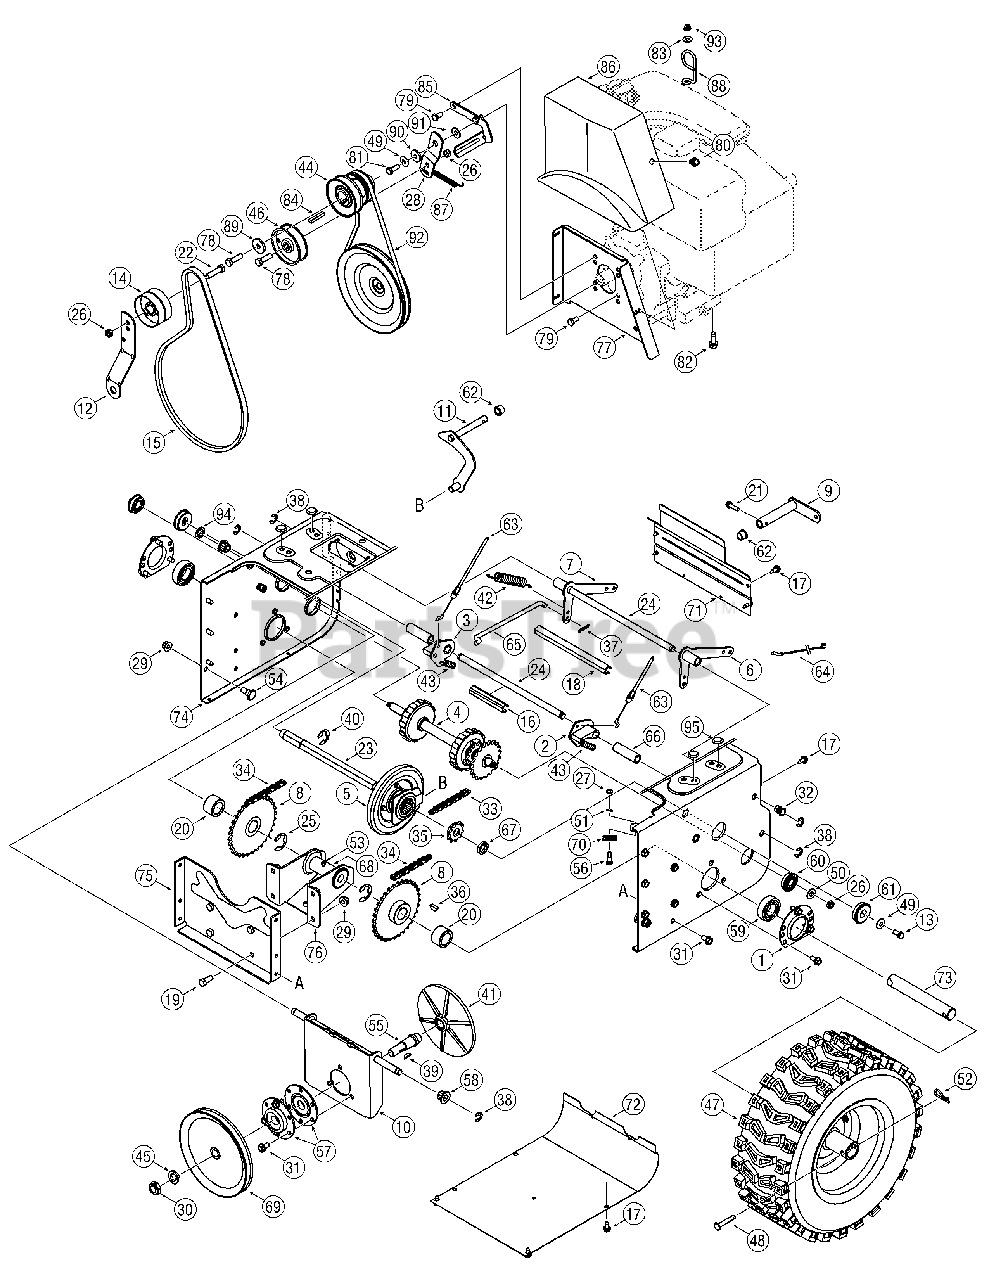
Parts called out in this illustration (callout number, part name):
1	Housing, Bearing
2	Dogg, Steering Drive, LH
3	Dogg, Steering Drive, RH
4	Shaft Assembly, Steering
5	Assembly, Friction Wheel
11	Rod Assembly, Shift
12	Brkt., Idler, Auger
13	Screw, Hex Cap Lock,
14	Idler, Flat, 2.75 OD
15	V-Belt, 1/2 x 44.0
16	Spcr., .51 ID x 3.66 Lg.
17	Screw, Hex Wash.
18	Spcr., .51 ID x 7.895 Lg.
19	Screw, Hex Cap, 3/8-16
20	Spcr., 1.0 ID x 1.50 OD
21	Screw, Hex, 1/4-20 x 1.00
22	Screw, 3/8-24 x 1.50
23	Shaft, Hex Drive
24	Shaft, Actuator
25	Ring, Retainer
26	Nut, Hex Insert Jam Lock
27	Nut, Hex, 1/4-28 GR5
28	Bracket, Idler, Drive
29	Nut, Hx Flnge Insert Lk
30	Nut, Hx Insert Jam Lk
31	TT Screw, 5/16-18 x .750
32	Nut, Insert 3/8-16
33	Chain, Endless, #41 x 36L
34	Chain, #420 x 40L
35	Sprocket, #41 x 10T
36	Key, Woodruff
37	Pin, Internal Cotter
38	E-Ring
39	Key, Hi-Pro, 3/16 x 5/8
40	Ring, Retaining
41	Plate, Drive
42	Spring, Extension
43	Spring, Extension
44	Pulley, Dbl, 3.25 OD
45	Washer, Lock, 5/8
46	Pulley, Flat Idler, 3.0 OD
48	Pin, Clevis
49	Wsh, Bell., .34 x .872 x .06
50	Wash, .406 x .875 x .059
51	Washer, Lock, 1/4
52	Pin, Internal Cotter
53	Fitting, Lube, 3/16 Drive
54	Screw, Shldr., .498 x .34
55	Spindle, Drive Plate
56	Screw, Hex Shldr., 1/4-28
57	Ass’y, Bearing/Housing
58	Bearing, Hex Flange
59	Bearing, Self Aligning
60	Bearing, Ball
61	Bearing, Ball
62	Bush, Flg, .5 ID x .627 OD
63	Cable, Steering
64	Cable, Auger Idler
65	Rod, Drive Clutch
66	Spcr., .514 x .632 x 2.44
67	Spacer, .675 x 1.0 x .23
68	Spcr, .6725 x 1.125 x 2.48
69	Pulley, Drive
70	Roller, Cable
73	Axle, Wheel, 45"
78	Screw, 3/8-14 x 1.25 GR8
79	Screw, 5/16-24 x .625
80	Screw, Hx Wash Hd Tapp
81	Screw, Hx Cap 5/16-24
82	Screw, 3/8-16 x 1.00
83	Wsh, Flat, .28 x .74 x .063
84	Key, Square, 1/4 x 1.5
86	Cover, Belt
87	Spring, Extension
88	Guide, Chute Cable
89	Washer, Flat, .406 x 1.25
90	Spacer, Shoulder
91	Washer, Flat, .349 x .879
92	V-Belt, 3/8 x 35.5
93	Nut, Flg Lk, 1/4-20
94	Nut, Spd.
95	Plug, 3/8 ID
